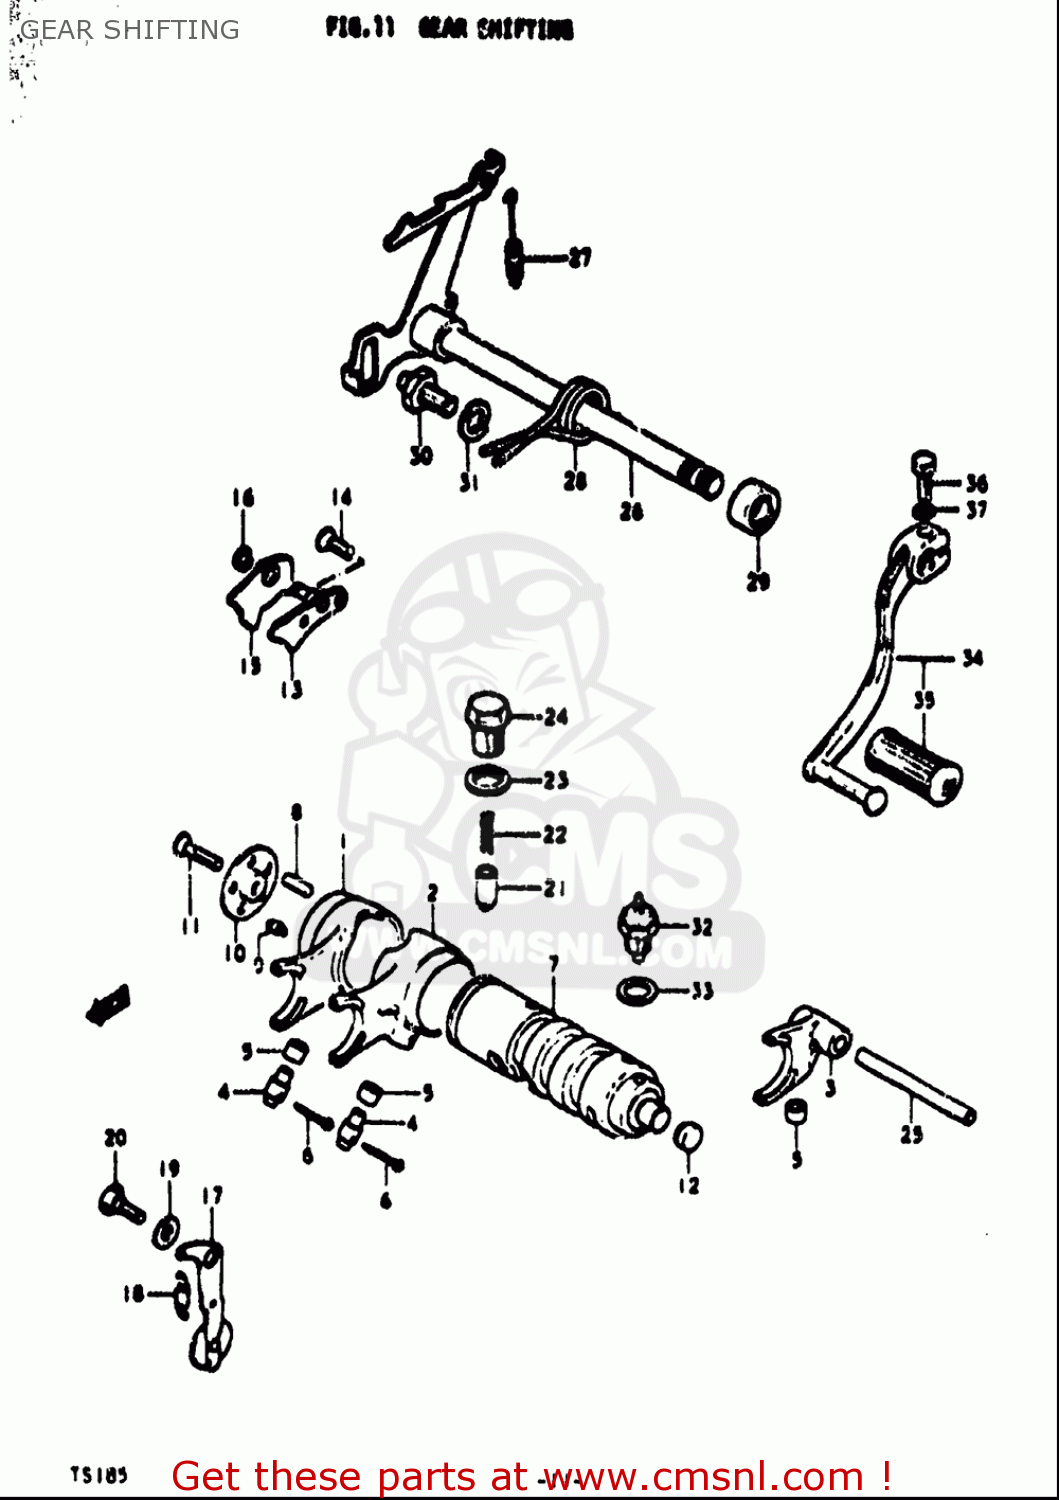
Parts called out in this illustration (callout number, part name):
1	FORK,GEAR SHIFT NO.1
2	FORK,GEAR SHIFT NO.2
4	PIN
5	SPACER(6X9.8X6)
6	PIN
8	ROLLER(4X13.8)
9	PIN
10	RETAINER,GEAR SHIFT CAM DR PIN
11	SCREW
12	PLUG
13	GUIDE,GEAR SHIFT CAM
14	SCREW
15	PAWL,GEAR SHIFT CAM STOPPER
16	E RING
17	STOPPER,GEAR SHIFT CAM
18	SPRING
19	WASHER(6.5X16X2.3)
20	BOLT(6X16.1)
21	STOPPER,GEAR SHIFT CAM
22	SPRING
23	GASKET(14X19.2X2) (NAS)
24	HOUSING,GEAR SHIFT CAM STOPPER
25	SHAFT,GEAR SHIFT FORK
26	SHAFT,GEAR SHIFT
28	SPRING
29	SEAL,OIL (12X22X9)
31	WASHER,LOCK
33	GASKET(12.5X20X1) (NAS)
34	LEVER ASSY,GEAR SHIFT
35	RUBBER,GEAR SHIFT PEDAL
36	BOLT
37	WASHER,LOCK
